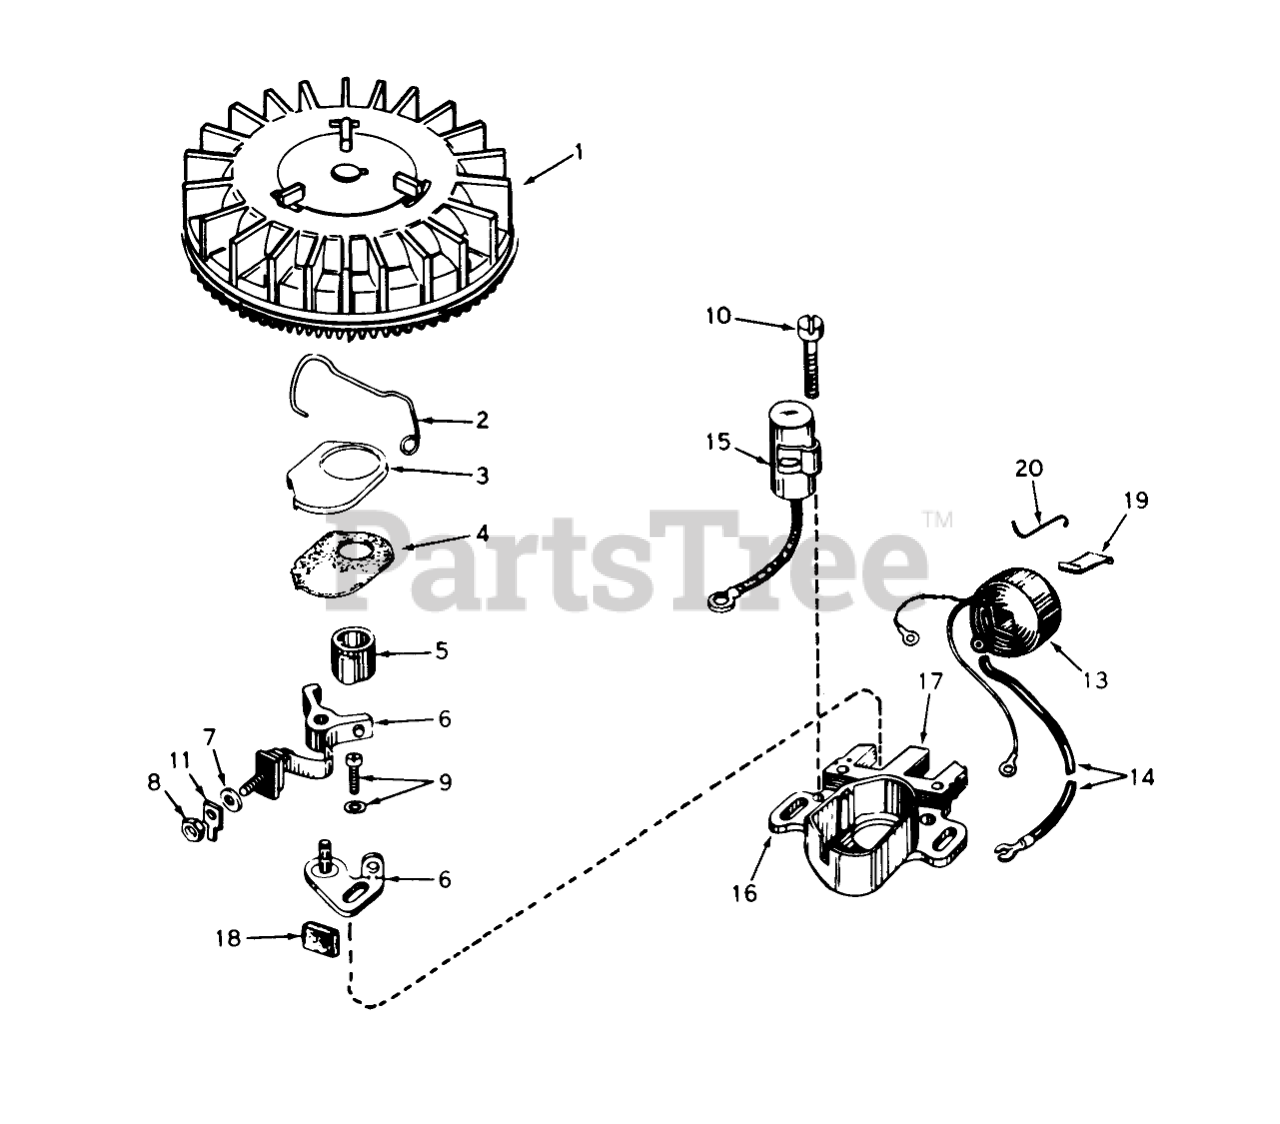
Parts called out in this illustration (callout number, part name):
1	Flywheel (Incl. Ref. #3 & 4)
2	Spring Breaker Box
3	Cover-Dust
4	Gasket, Dust Cover
5	Cam, Breaker
6	Breaker Assy.
9	Breaker Screw
10	Condenser Screw
11	Terminal, Ground
13	Coil Assembly (Incl. Ref. #14)
14	Wire, Lead
15	Condenser
16	Core & Plate
17	B Stator Assembly (Incl. Ref. #2, 3, 4, 6 thru 16, 18, 19 & 20)
18	Felt,Cam Wiper
19	Spring Coil Wedge
20	Clip, Coil
